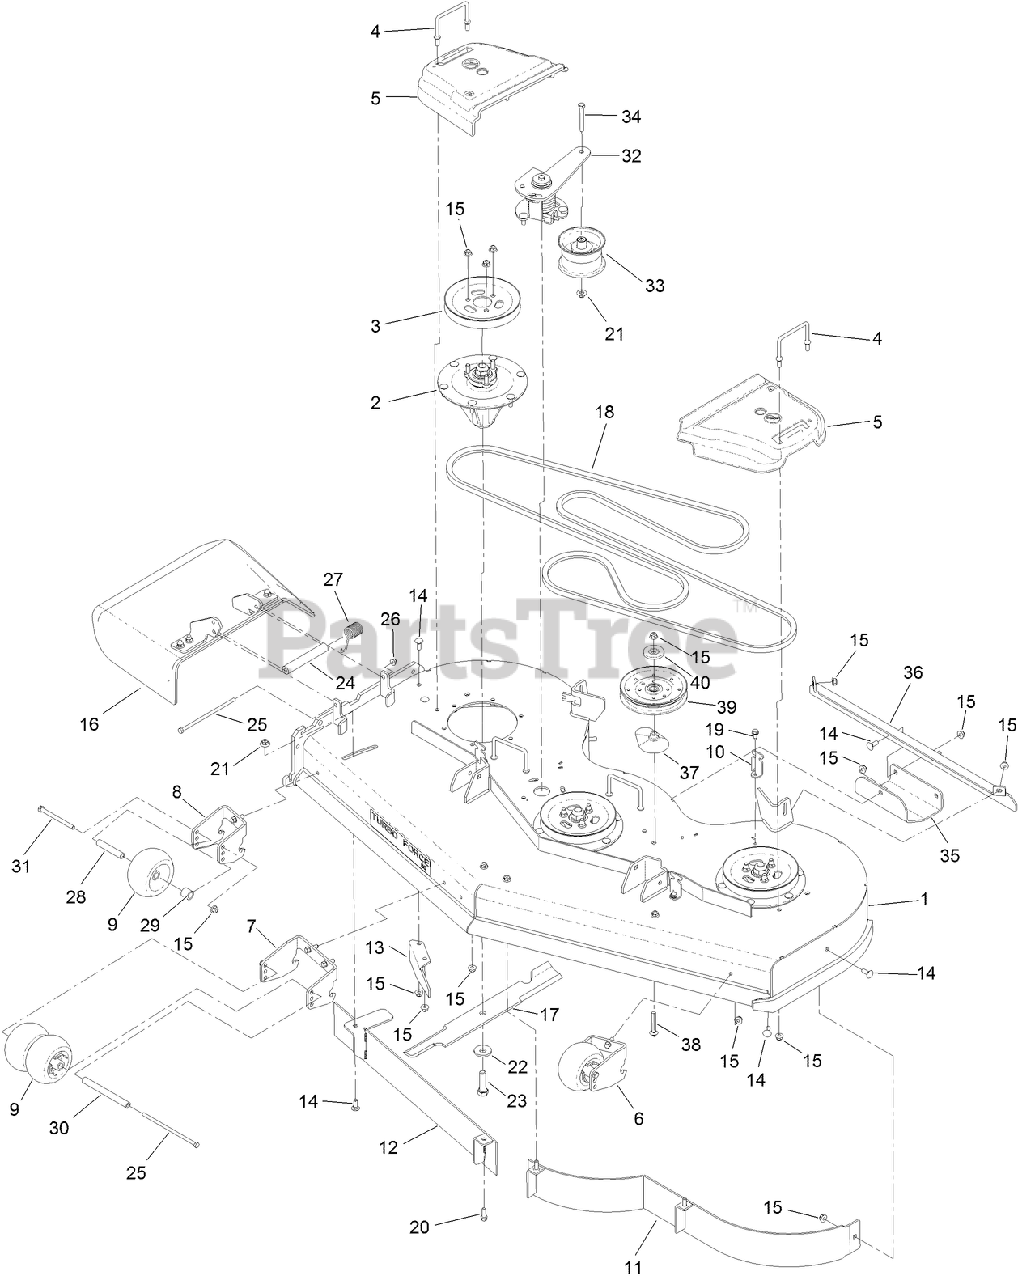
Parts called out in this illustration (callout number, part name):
1	DECK ASM
2	SPINDLE ASM
3	PULLEY
4	WIREFORM-COVER
5	COVER-BELT, LH
6	BRACKET-WHEEL, LH
7	BRACKET-WHEEL, CENTER
8	BRACKET-WHEEL, RH
9	ROLLER-SCALP, ANTI
10	BRACKET-COVER
11	BAFFLE ASM
12	BAFFLE ASM
13	BAFFLE-DISCHARGE
14	SCREW-HH
15	NUT-HF, NI
16	DEFLECTOR ASM
17	BLADE-HI FLOW
18	BELT-V
19	SCREW-HWHTF
21	NUT-FLANGE, NI
22	WASHER-BLADE BOLT, HEAVY
23	SCREW-BLADE
24	SPACER
25	SCREW-HH
26	NUT-HF, NI
27	SPRING-TORSION
28	TUBE-SPANNER
29	SPACER-AXLE, REAR
30	SPACER-WHEEL
31	SCREW-HH
33	PULLEY-IDLER
34	SCREW-HH
36	BRACKET-SKID
37	SPACER-PULLEY
38	SCREW-CARR
40	SHIELD-DUST
